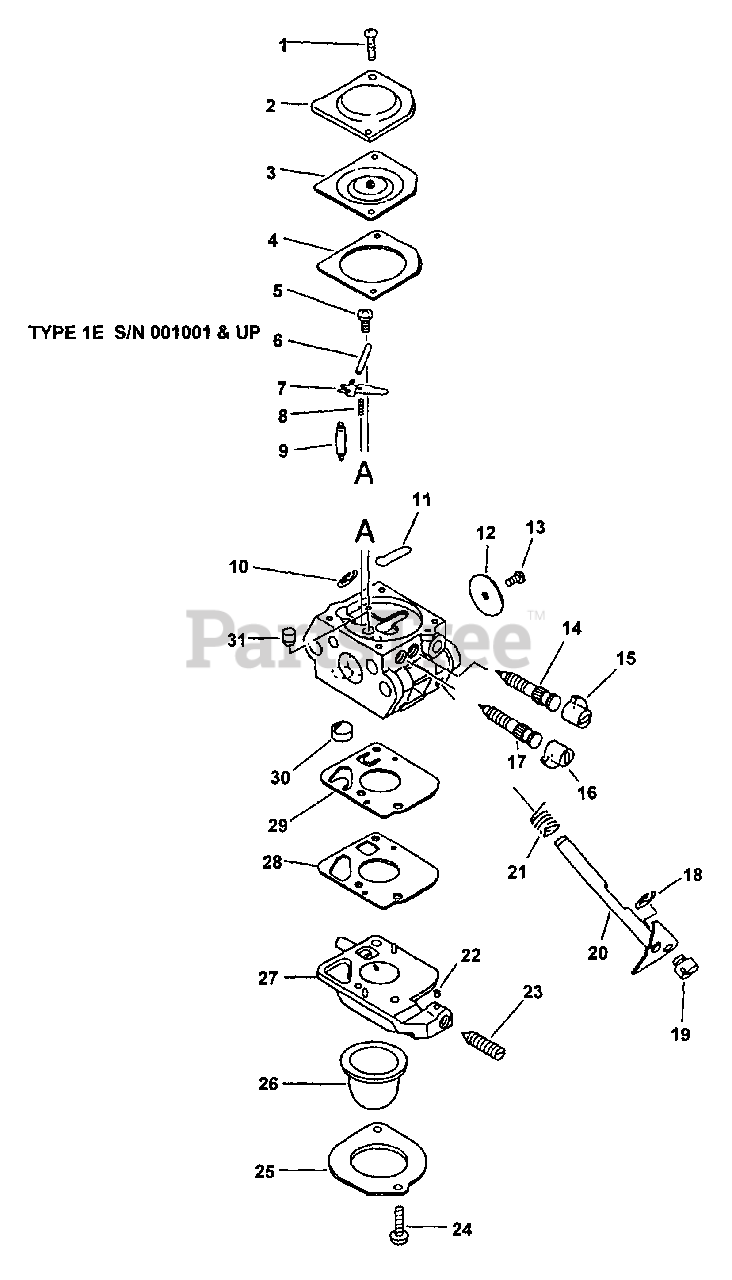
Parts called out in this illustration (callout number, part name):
2	COVER, METERING DIAPHRAGM
3	DIAPHRAGM, METERING
4	GASKET, METERING
6	PIN, METERING LEVER
7	LEVER, METERING
8	SPRING, METERING LEVER
9	VALVE, NEEDLE
11	PLUG, WELCH
12	VALVE, THROTTLE
14	NEEDLE, LOW SPEED
15	CAP, LIMITER - WHITE
16	CAP, LIMITER - RED
17	NEEDLE, HIGH SPEED
20	SHAFT, THROTTLE
21	SPRING, THROTTLE RETURN
22	PIECE, FRICTION
23	SCREW, IDLE ADJUST
25	RETAINER
26	BULB, PURGE
27	BODY ASSY, PURGE
30	STRAINER
31	NOZZLE, CHECK VALVE
